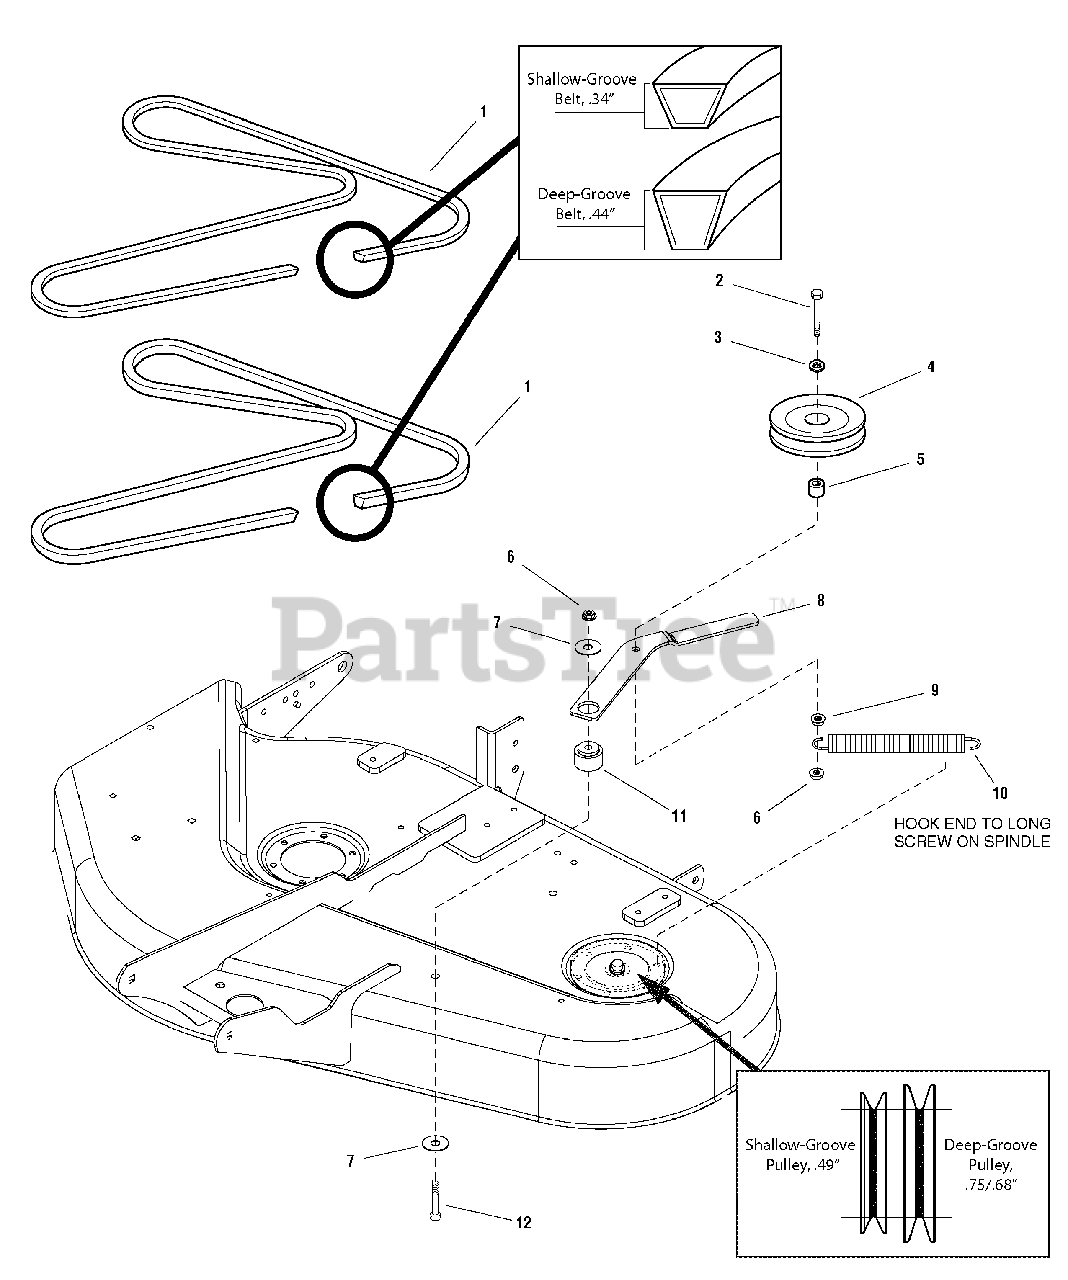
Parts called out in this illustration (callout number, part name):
1	V-BELT, Shallow-Groove, .34"
1	V-BELT, Deep-Groove, .44"
2	CAPSCREW, Hex Head, 3/8-16 x 2-1/2
3	WASHER, 3/8
4	PULLEY ASSEMBLY
5	SPACER
6	NUT, Hex, Flange, Locking, 3/8-16
7	WASHER, Plain, 13/32 x 1-1/2 x 1/8
8	ARM, Idler 7GA
9	NUT, Whizlock, 3/8-16
10	SPRING, Extension, Idler Arm
11	SPACER, 0.387 ID x 1-1/2 OD x 1.04 LG Powdered Metal
12	CAPSCREW, Hex Head, 3/8-16 x 2
